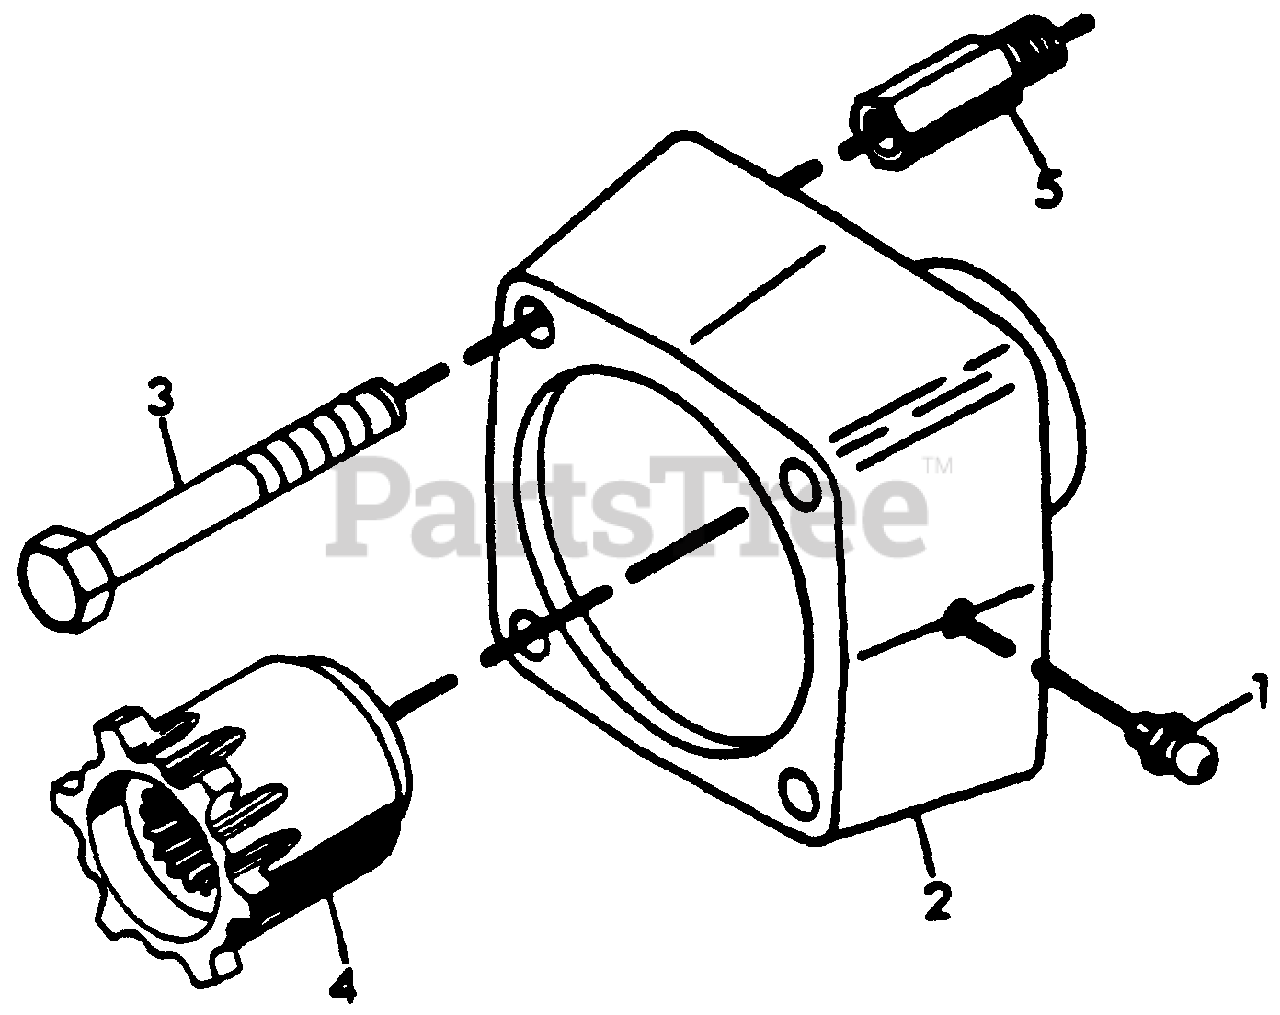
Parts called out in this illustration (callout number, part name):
1	FTG,LUBE, .25-28 SELF THREAD
2	ADPT,
3	BLT-HEX .50-13X4.00 GR5 YWZC
4	DOG,ATTACHMENT
5	STUD,QUICK HITCH
